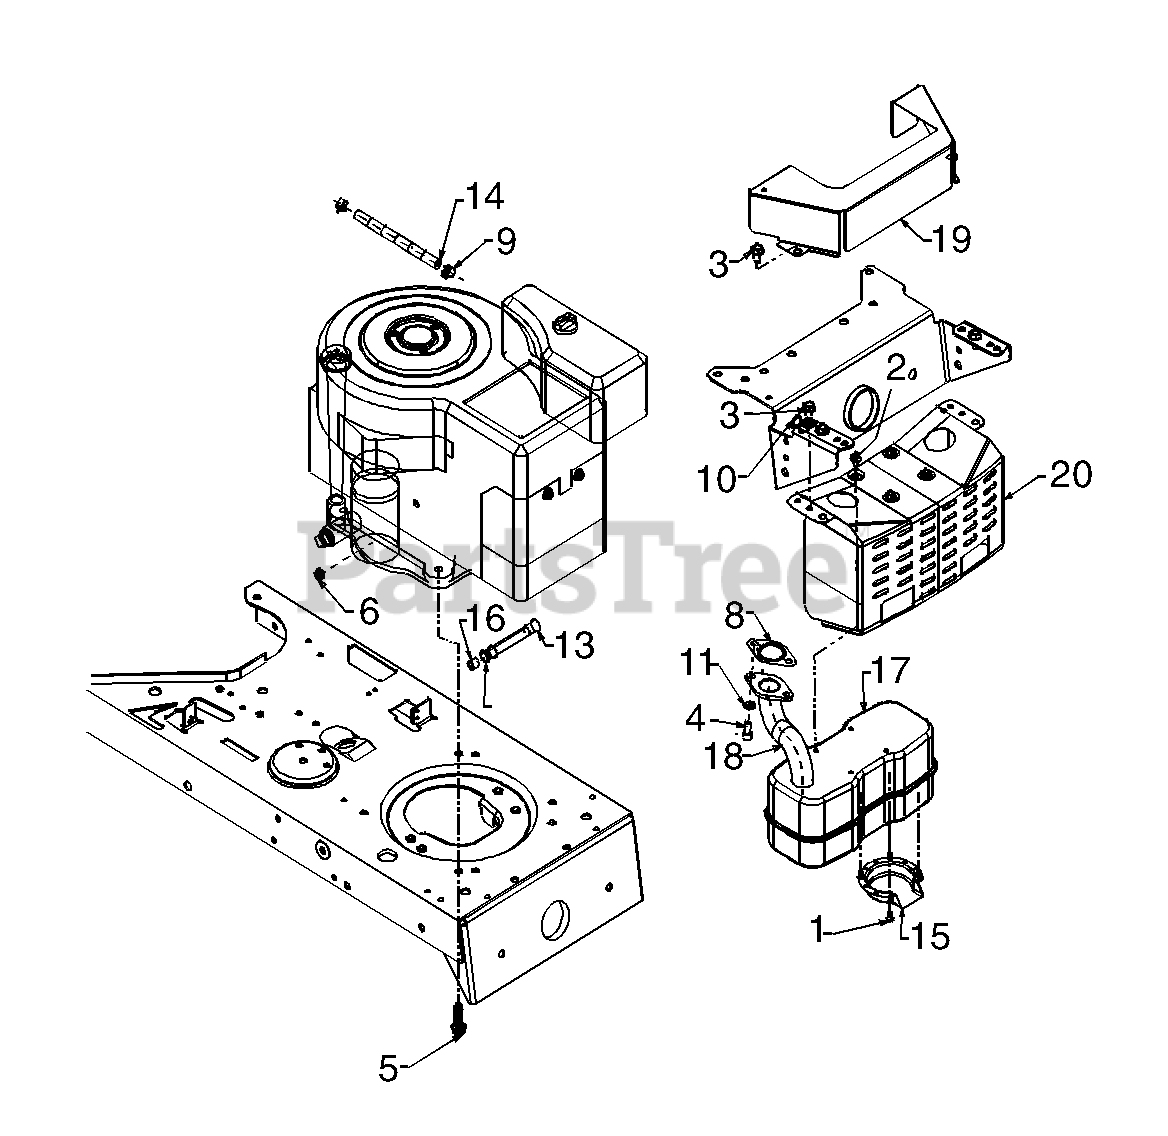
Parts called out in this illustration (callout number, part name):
1	Hex Bolt #8-32 x .38" Lg.
2	Hex Wash. Hd. TT-Scr. 1/4-20 x .5"
3	Hex Wash. Hd. TT-Scr. 5/16-18 x .62"
4	Socket Hd. Bolt 5/16-18 x .62" Lg.
5	Hex Wash. Hd. TT-Scr. 3/8-16 x 1.25"
6	Hex Sems Nut 1/4-20 Thd.
8	Exhaust Gasket
9	Hose Clamp
10	Clamp
11	L-Wash. 5/16" I.D.
13	Pipe 3/8 NPT x 3.8" Lg.
14	Fuel Line
15	Muffler Deflector
16	Hex Pipe Plug
17	Muffler
18	Exhaust Pipe
